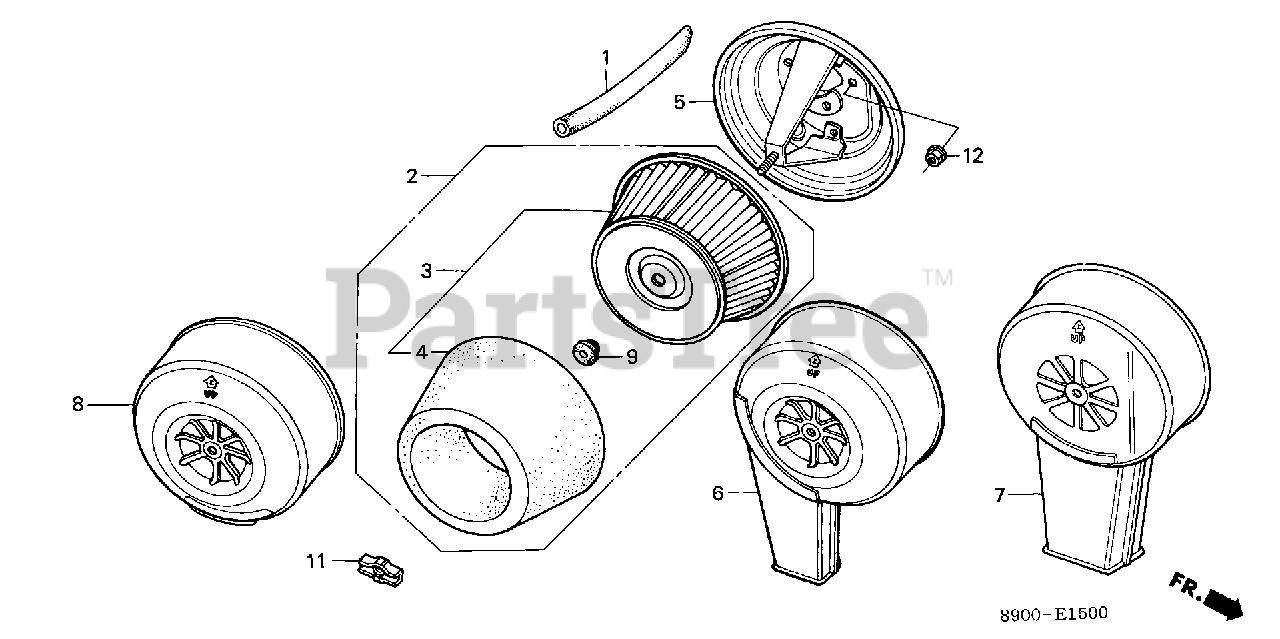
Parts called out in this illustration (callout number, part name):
1	TUBE, BREATHER
3	ELEMENT, AIR CLEANER
4	FILTER (OUTER)
5	HOUSING, AIR CLEANER
5	HOUSING, AIR CLEANER (NOT AVAILABLE)
6	COVER, AIR CLEANER
7	COVER, AIR CLEANER
8	COVER, AIR CLEANER
9	GROMMET, AIR CLEANER
11	NUT, AIR CLEANER COVER (DACRO COATING)
12	NUT, FLANGE (6MM)
